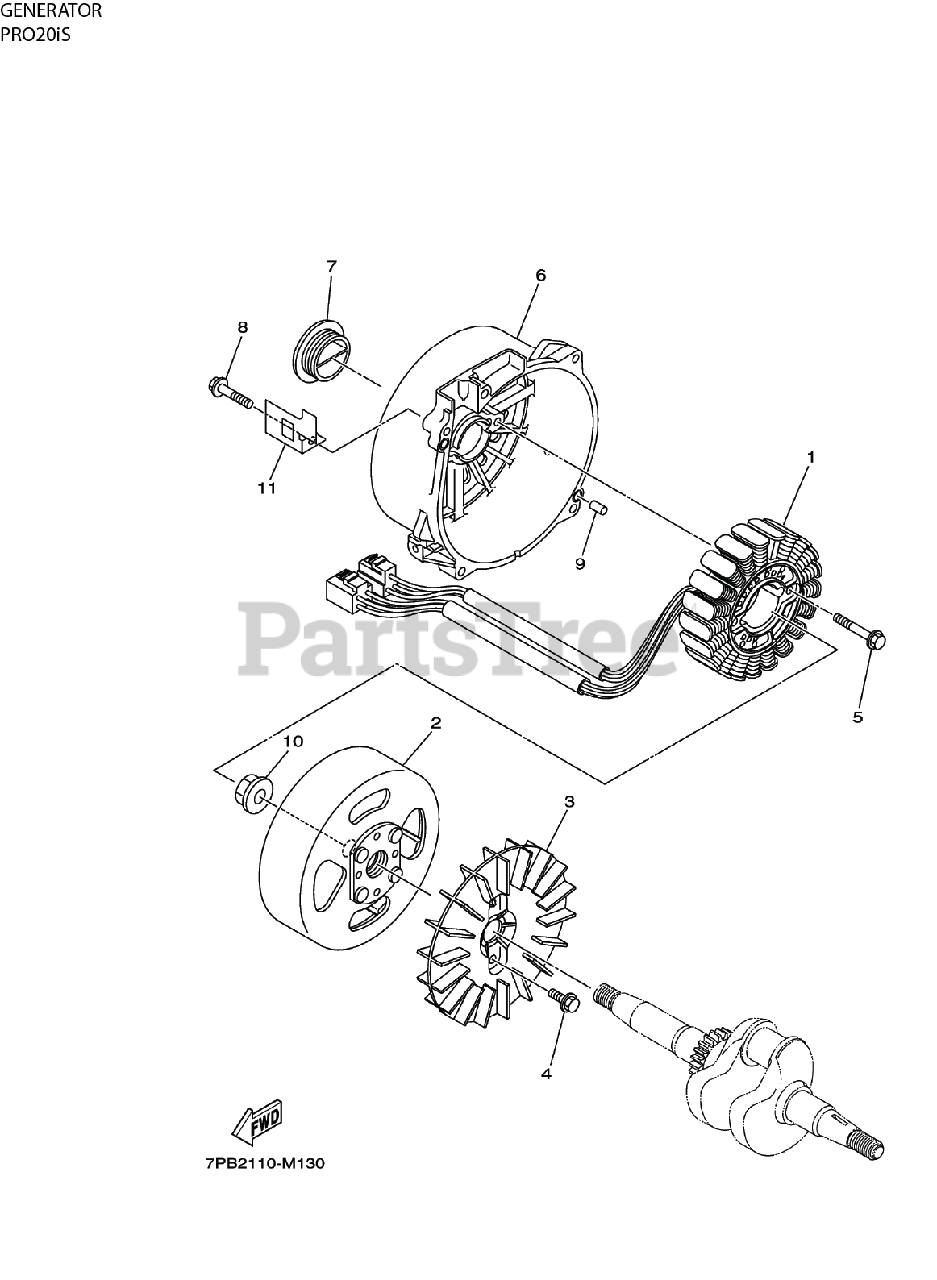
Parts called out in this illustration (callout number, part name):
1	STATOR ASSEMBLY
2	FLYWHEEL, ROTOR ASSEMBLY
3	FAN, GENERATOR
4	SCREW - BOLT FLANGE
5	SCREW - BOLT
6	HOUSING, COVER REAR END
8	SCREW - BOLT FLANGE
9	CRANKCASE 1
